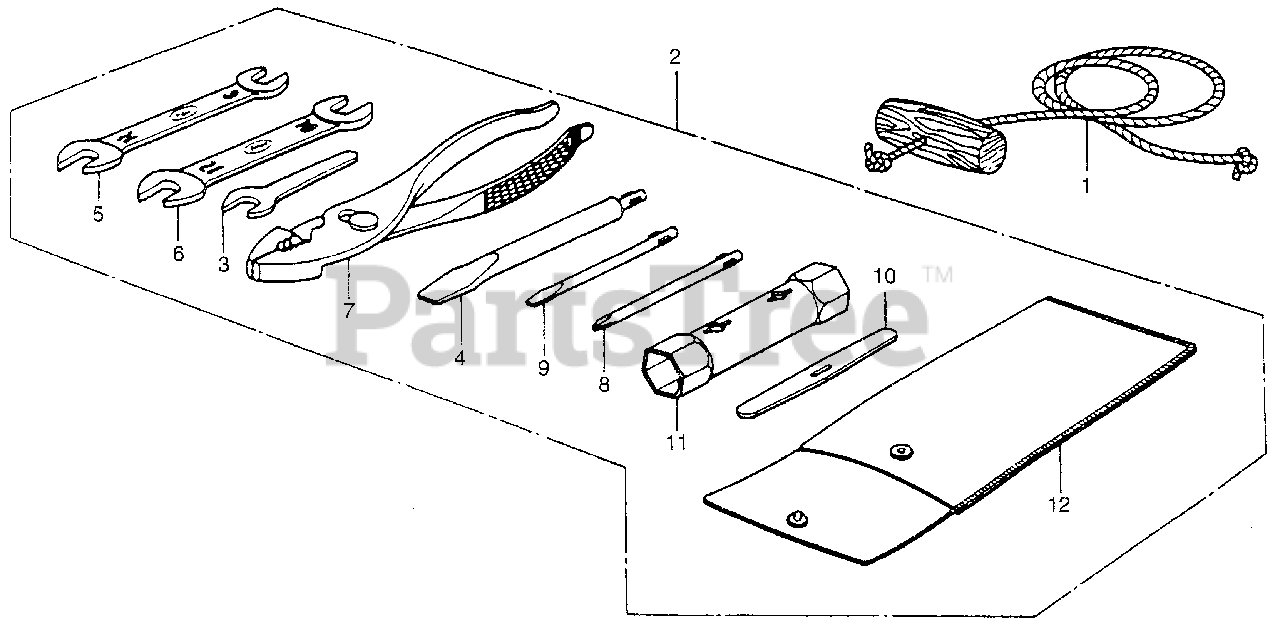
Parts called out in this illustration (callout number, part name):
1	ROPE, STARTER (#5X55")
2	TOOL SET (N/A: SEE COMPONENTS)
3	WRENCH (8MM) (OPEN END)
4	SCREWDRIVER, CHECK BOLT
5	WRENCH (9X12) (OPEN END)
6	WRENCH (10X12) (OPEN END)
7	PLIERS (135MM)
8	SCREWDRIVER 1, PHILLIPS (NO.2)
9	SCREWDRIVER 3, STRAIGHT SLOT (NO. 2)
10	LEVER, TIRE
11	WRENCH, BOX (P18X19)
12	BAG, TOOL
